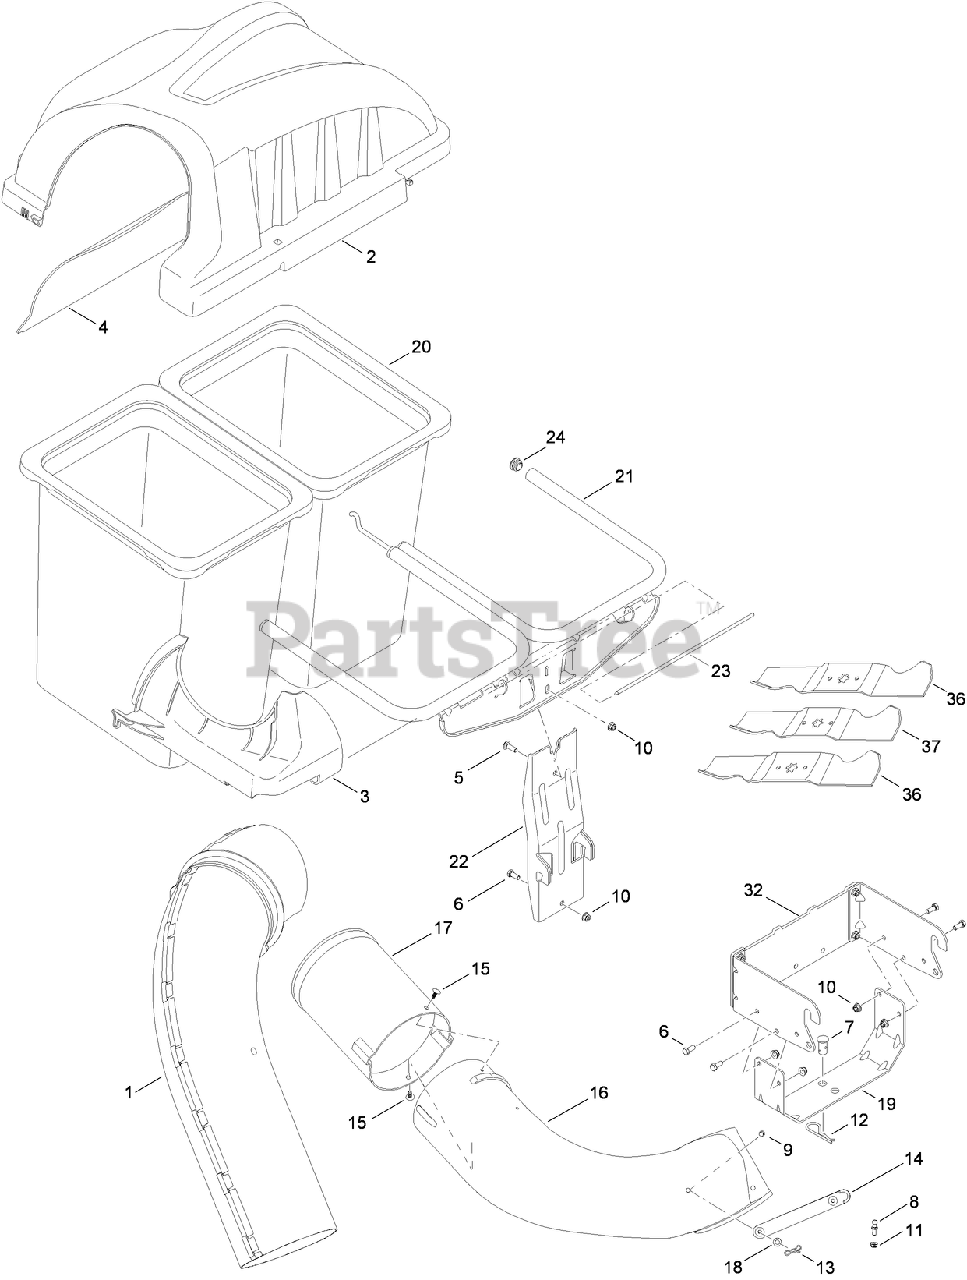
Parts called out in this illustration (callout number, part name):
1	UPPER CHUTE ASM
2	DOUBLE BAGGER COVER ASM
3	SUPPORT-CHUTE, UPPER
4	SCREEN-COVER, BAGGER
5	BOLT-CARR
6	SCREW-HH
7	PIN-CLEVIS
8	PIN-CATCHER, GRASS
9	PIN-CLEVIS
10	NUT-LOCK, FLANGE
11	NUT-LOCK, FLANGE
12	CLIP-HAIRPIN
13	PIN-COTTER
14	STRAP-CHUTE
15	CLIP-RATCHET, FASTENER
16	CHUTE-DISCHARGE
17	ADAPTER-CHUTE, BAGGER
18	WASHER-BELL
19	SUPPORT-BRACKET, UNIVERSAL
20	GRASS BAG ASM
21	DOUBLE BAG SUPPORT ASM
22	BRACKET-SUPPORT, VERTICAL
23	PIN-HINGE, COVER
24	PLUG-END
32	HITCH BRACKET ASM
36	BLADE (2 IN 1 STAR, 16.28 INCH)
37	BLADE (2 IN 1 STAR, 14.88 INCH)
